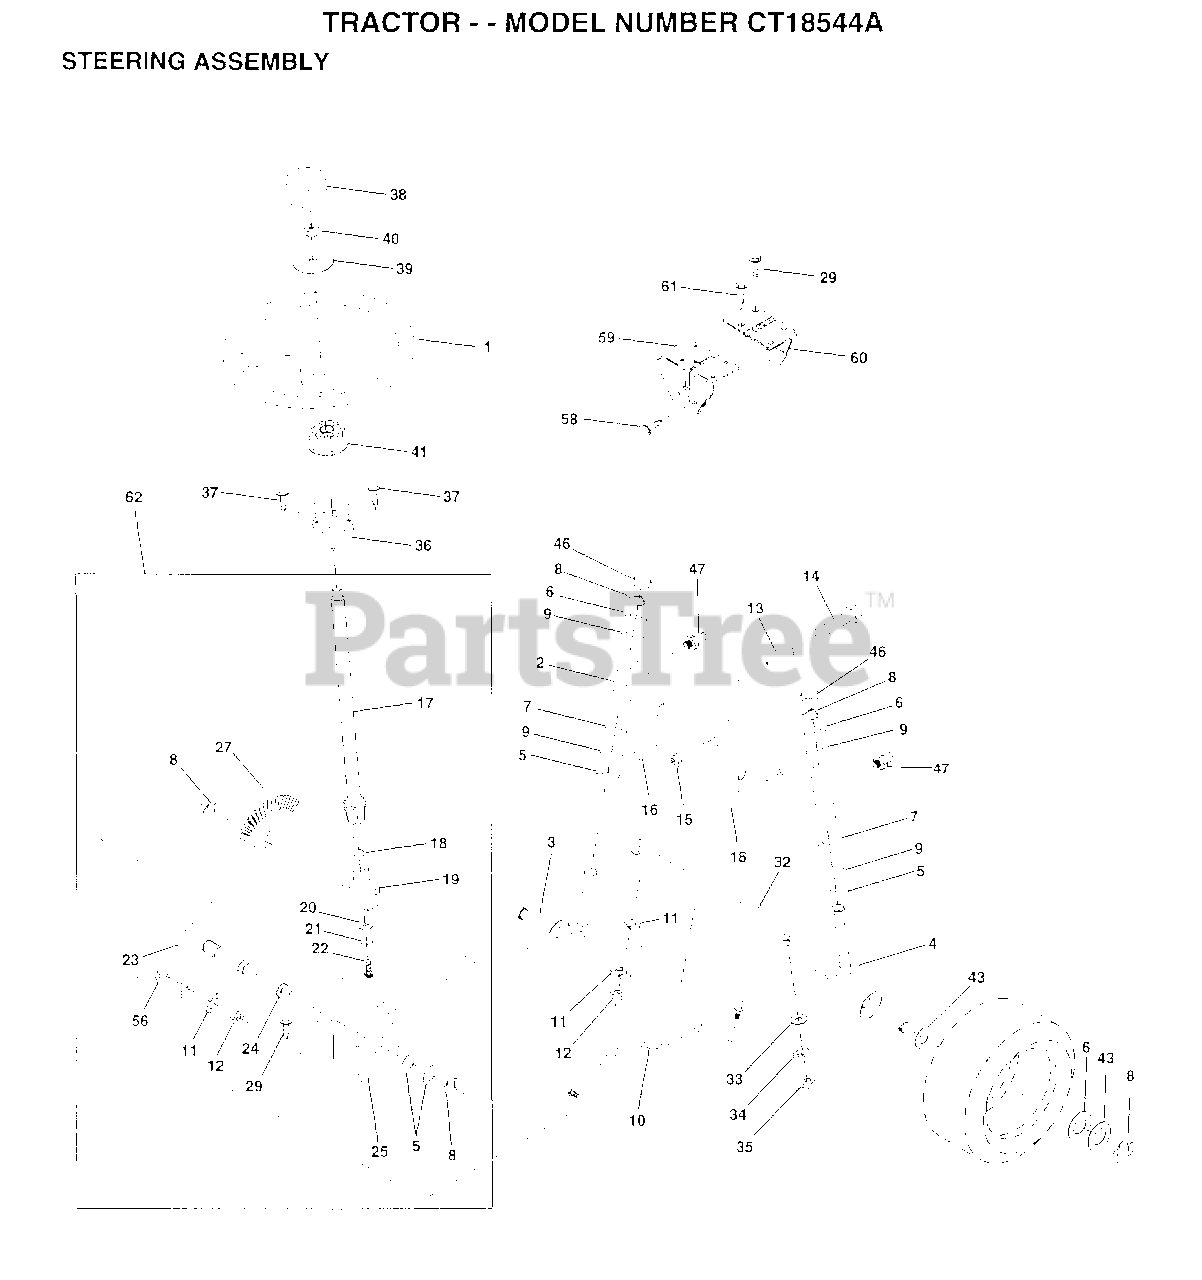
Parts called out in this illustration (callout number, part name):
1	WHEEL STR AYP BLK
2	AXLE ASM FRONT
5	WASHER .T
6	WASHER
7	WASHER
8	RING
9	COL. SRTG. BEAR.
11	LOCKWASHER
13	BEARING
14	BOLT LT
15	"NUT-LOC,FLANGE LT"
16	AXLE PIN
18	THRUST WASHER
19	SUPPORT.SHAFT
21	LOCKWASHER
22	SCREW.SCKTHD.CAP
24	NYLINER T
25	"BRKT,STEERING"
27	GEAR SECTOR
29	SCREW
32	TIE ROD
33	WASHER M
34	LOCKWASHER
35	NUT.LOCK.5/16-24
36	BUSHING.STRG.3/4
37	SCREW.10-24X1/2
38	CAP STEER AYP
39	WASHER
41	ADAPTER LT
43	WASHER
46	CAP
47	ZERK M
56	WASHER
58	SCREW LT
59	SUPPORT-SADDL T
60	SUPPORT.SADDLE.FT
61	SCREW SPECIAL
62	KIT.STEER.20.31
